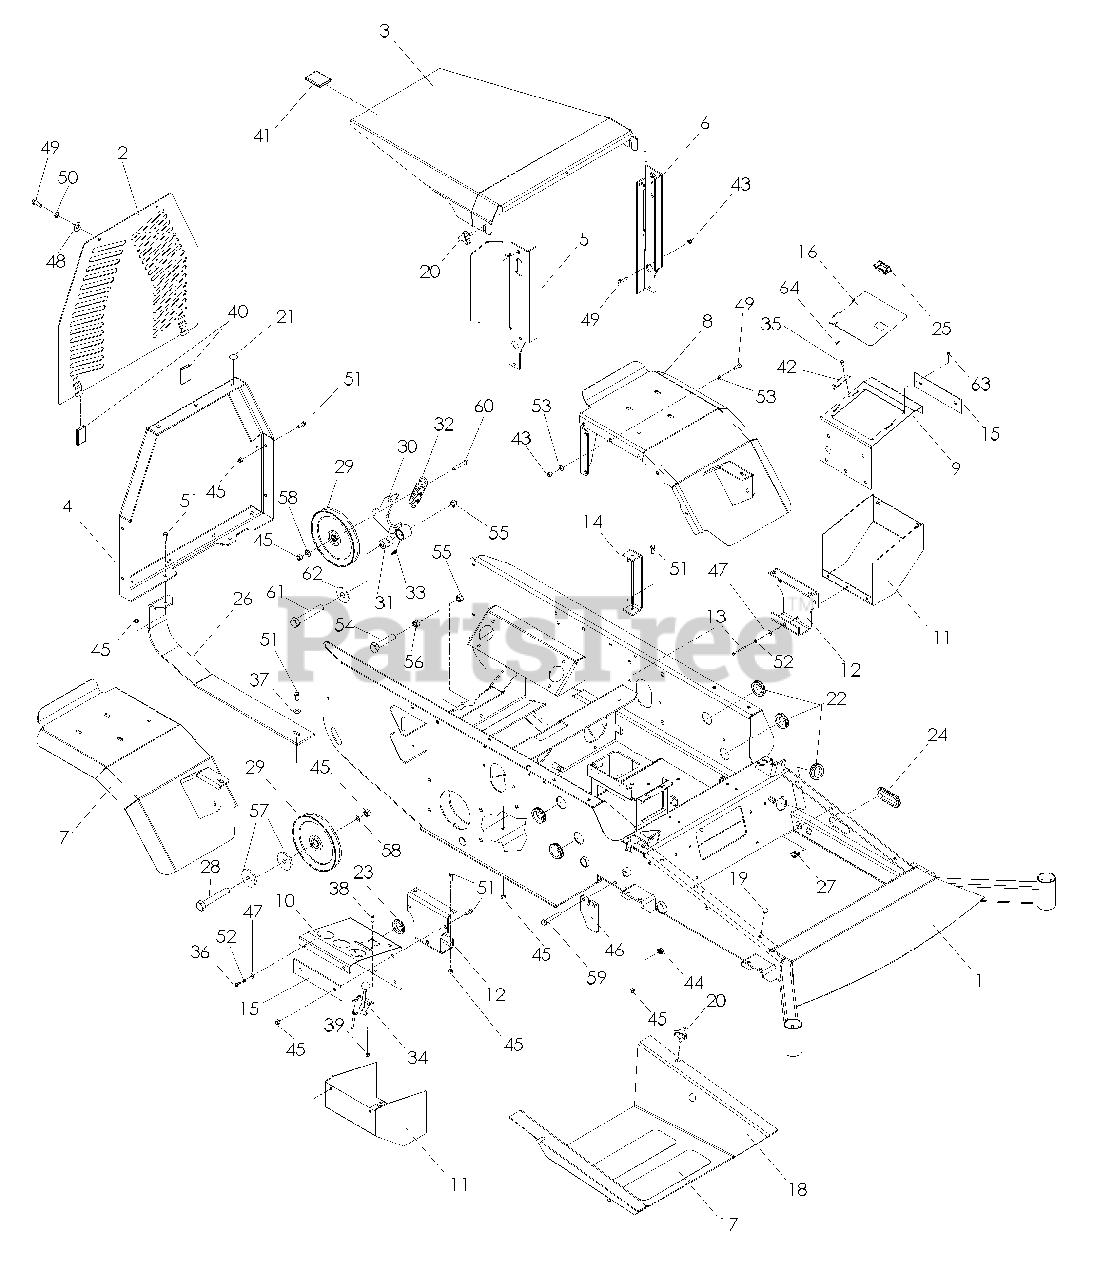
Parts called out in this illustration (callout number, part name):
1	FRAME w/DECALS
2	BACK PANEL
4	REAR FRAME
5	SUPPORT, RT
6	SUPPORT, LT
7	FENDER WELDMENT, RT
8	FENDER WELDMENT, LT
9	CONSOLE TOP
10	CONTROL PANEL
11	CONSOLE BOTTOM
12	CONSOLE SUPPORT
13	HCS 1/4-20 x 3
14	SUPPORT WELDMENT
16	DOOR-FINISHED
17	ABRASIVE PAD
18	FLOOR PAN WELDMENT
19	RUBBER STOP
20	KNOB w/ STUD
21	GROMMET BUMPER
26	SKID PLATE
27	RETAINER, 5/16-18 U-TYPE
28	HCS 3/8-18 x2 1/2
33	ZERK
34	THROTTLE CABLE
35	SCREW 10-12 x 3/4 THD FRM
36	SCREW 1/4-20 x 5/8 THD FRM
37	WASHER 3/8 FLAT STD
38	HCS #10-24 x 1/2
39	NUT #10-24 HEX NYLOC
43	NUT 5/16-18 HEX NYLOC
44	NUT 5/16-18 WHIZ
45	NUT 3/8-16 HEX NYLOC
47	WASHER 1/4 FLAT
48	WASHER 5/16 STD FLT
49	HCS 5/16-18 x 1
50	WASHER 5/16 SLOTTED LOCK
51	HCS 3/8-16 x 1
52	WASHER 1/4 SPLIT LOCK
53	WASHER 5/16 FLAT SAE
54	HCS 1/2-13 x2 GR8
55	NUT 1/2-13 HEX NYLOC
56	NUT 1/2-13 HEX
57	WASHER HEAVY
58	WASHER 3/8 SAE FLT
59	HCS 5/16-18 x2 1/4
60	HCS 3/8-16 x2 1/4
61	HCS 1/2-13 x2 1/2
62	WASHER 1/2 FLAT
64	FOAM STRIP
